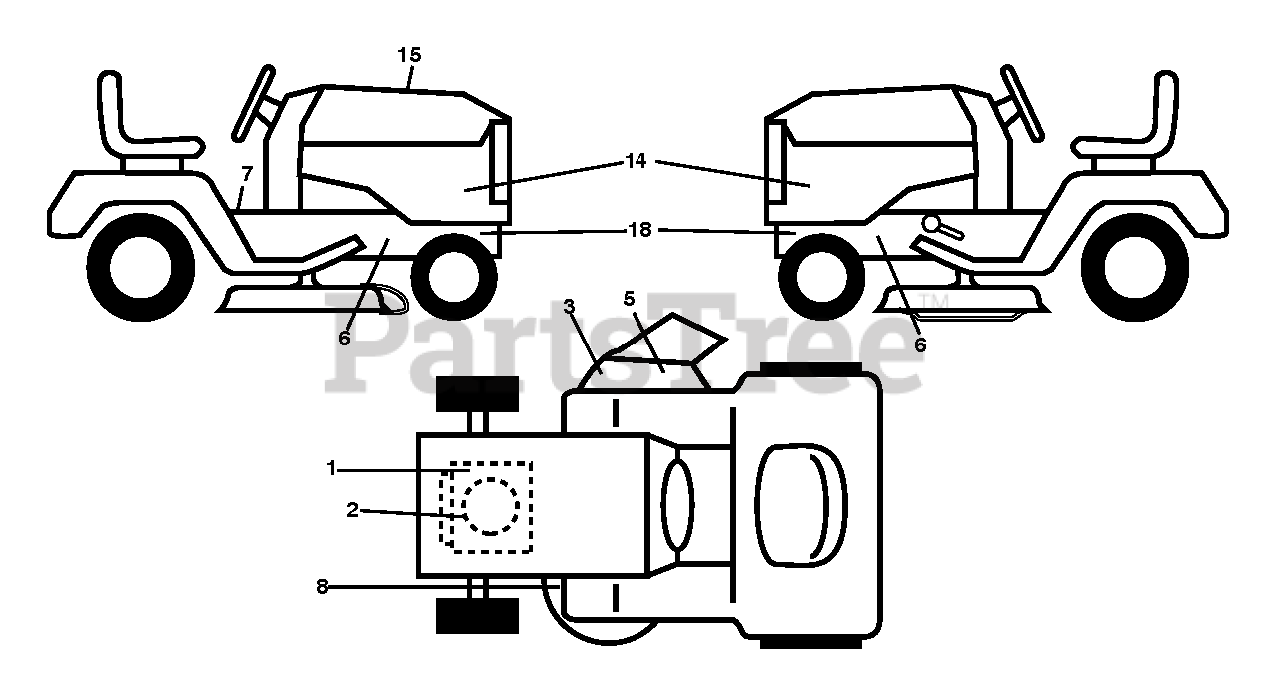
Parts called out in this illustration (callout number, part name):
1	DECAL.ENGINE.WARNING
2	DECAL.ENG.BS.656.ENDUR.382292
3	DECAL.DFLCTR.WARNNG.CTFNGR.SYM
5	DECAL.DECK.DEFLECTOR.WARNING
6	DECAL.WARNING.SERVCE/FIRE
7	DECAL TRACTOR SADDLE DECAL DEC
8	DECAL.DECK.BELT.ROUTE.42"2021
15	DECAL DECAL.RPL.BSM44.END.TLW.
18	DECAL.WARNING.HOT.MUFFLER.2021
